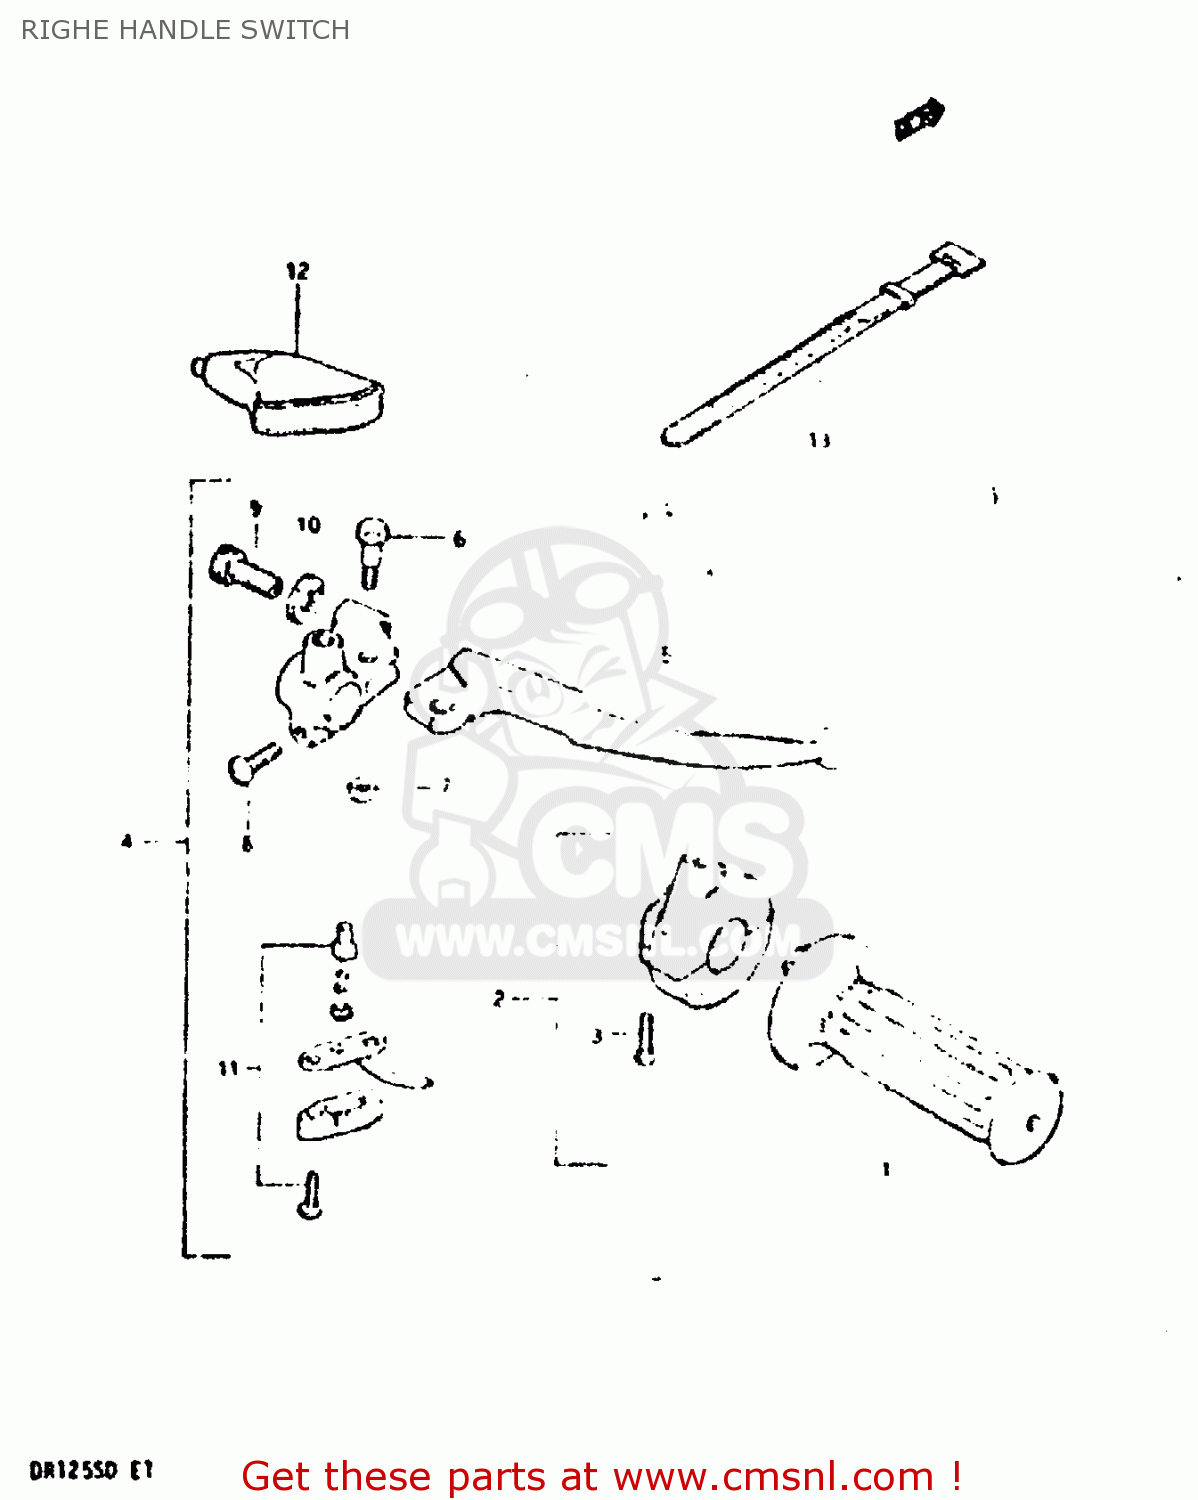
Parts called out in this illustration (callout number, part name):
1	GRIP,THROTTLE
2	CASE ASSY,THROTTLE
3	SCREW 5X20
4	LEVER ASSEMBLY,BRAKE
5	LEVER,BRAKE
6	BOLT,LEVER
7	NUT 6MM
8	SCREW
9	ADJUSTER,CABLE
10	NUT
12	COVER,CLUTCH LEVER
13	CLAMP(L:120)
